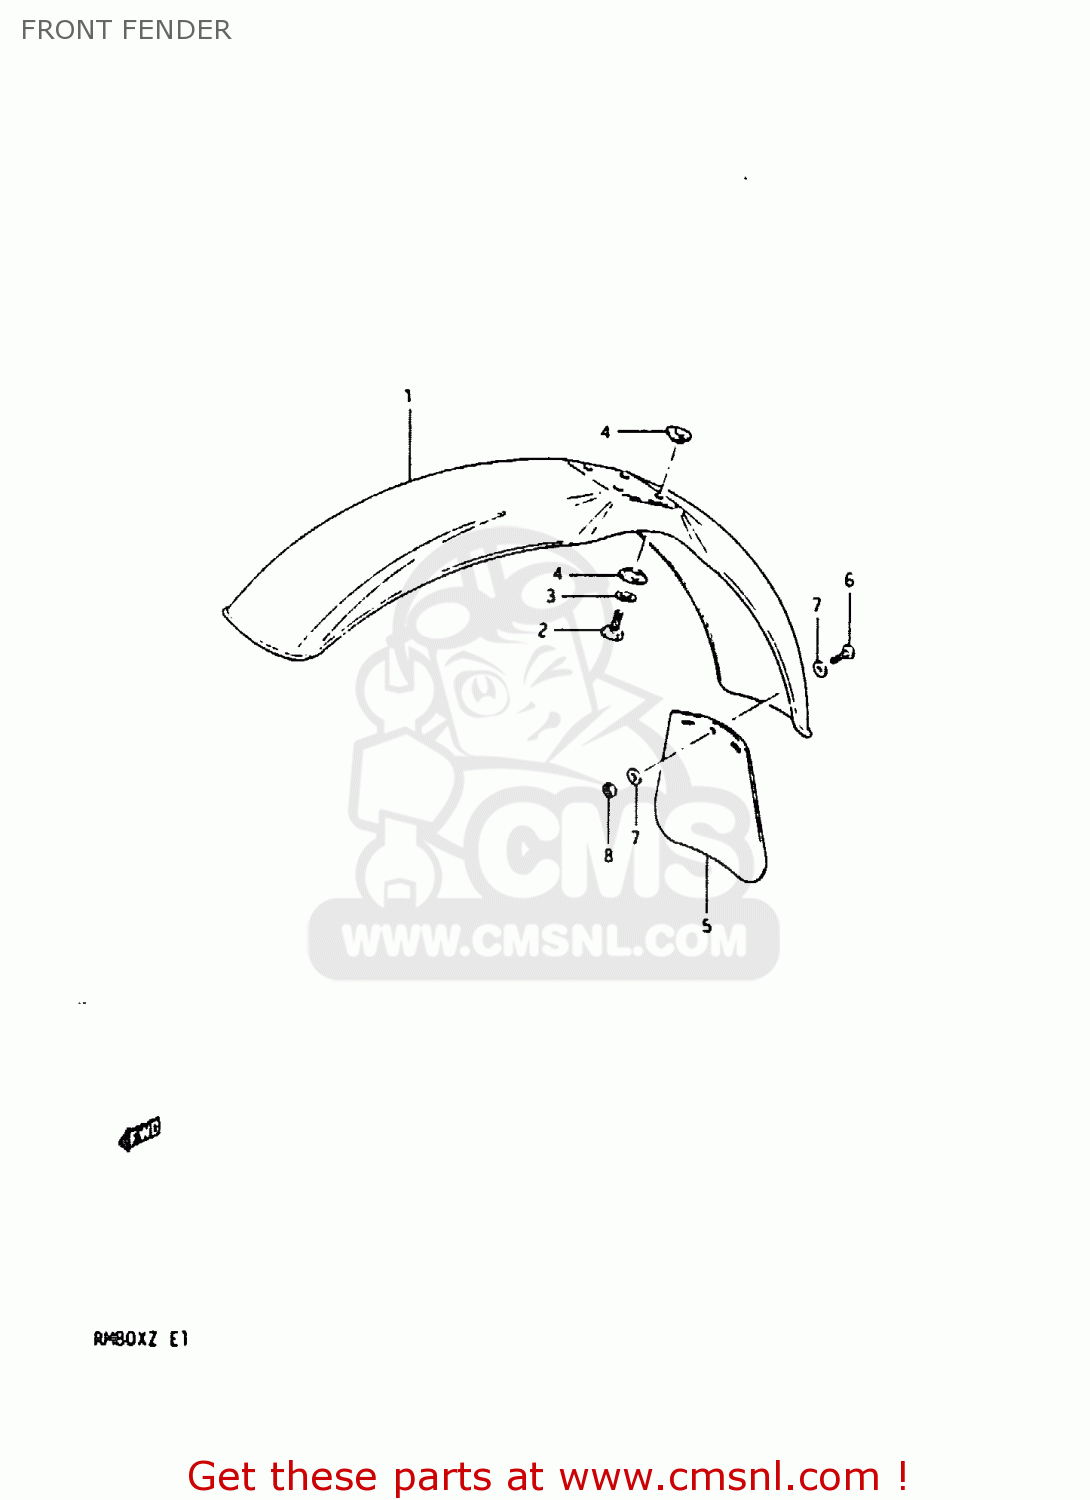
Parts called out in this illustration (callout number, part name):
1	FENDER,FRONT
2	BOLT, UPPER
3	LOCK WASHER
4	SPACER
5	MUD FLAP,FRONT FENDER
6	SCREW
7	WASHER
8	NUT
